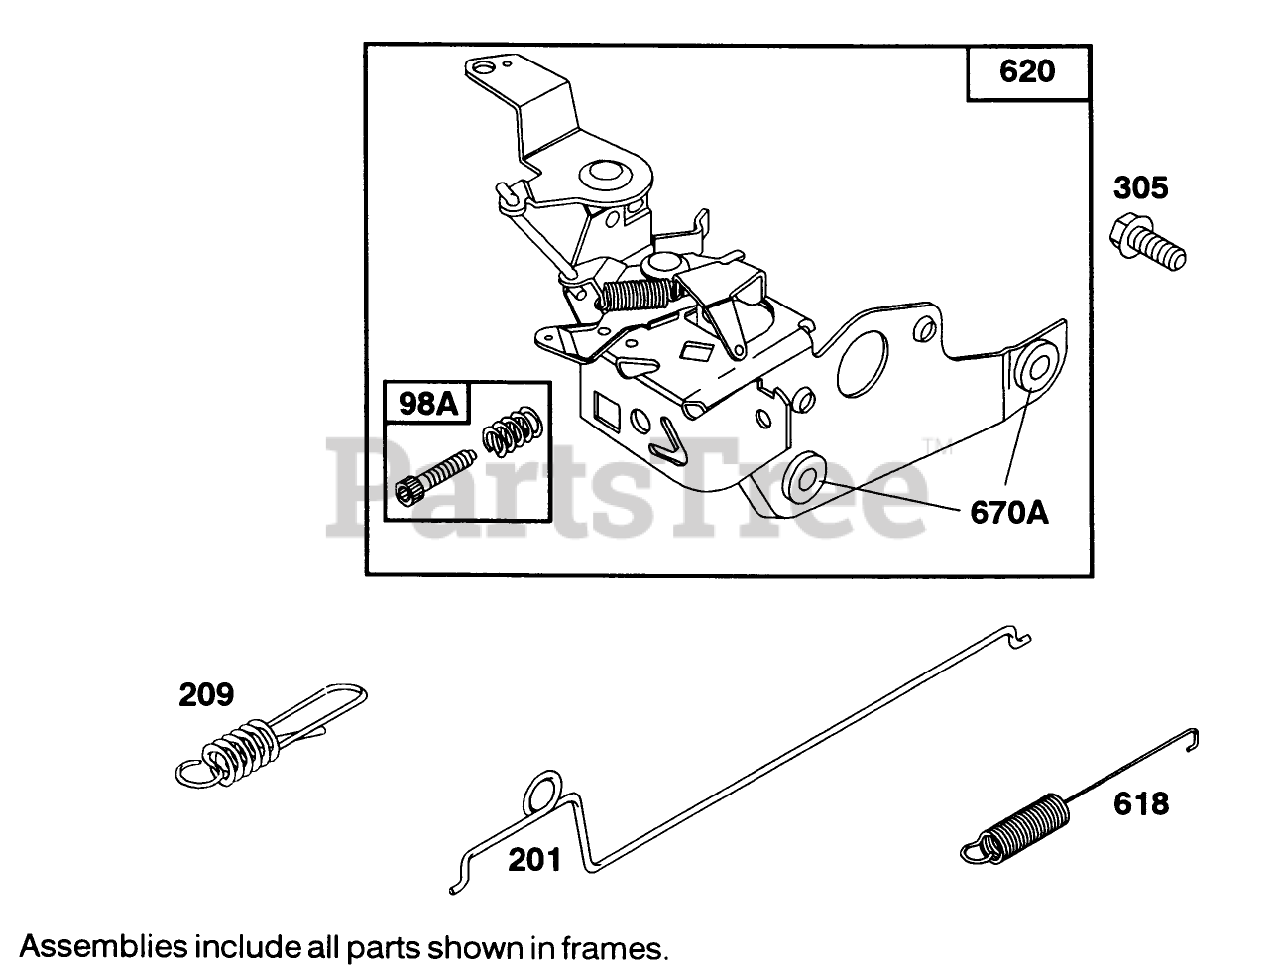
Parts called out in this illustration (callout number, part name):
98A	Screw Assy.
201	Link-Govemor
209	Spring-Govemor
305	Screw-Sem
618	Spring-Choke
620	Bracket Assembly
670A	Spacer
